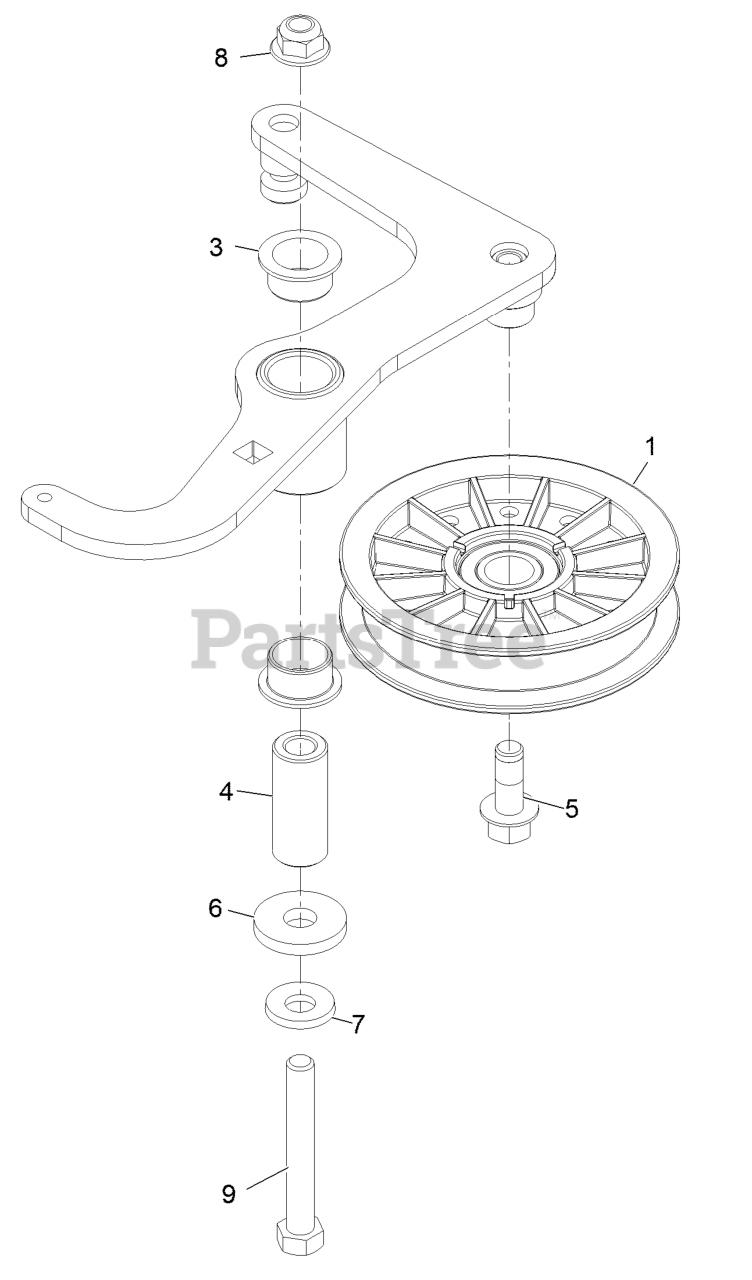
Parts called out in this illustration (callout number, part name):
1	Pulley-Idler, Flat
3	Bushing-Flanged
4	Spacer, Pivot
5	Screw-Hfh
7	Washer-Spring Disc 3/8
8	Nut-Nyloc 3/8-16 Flg
9	Screw-TAP
